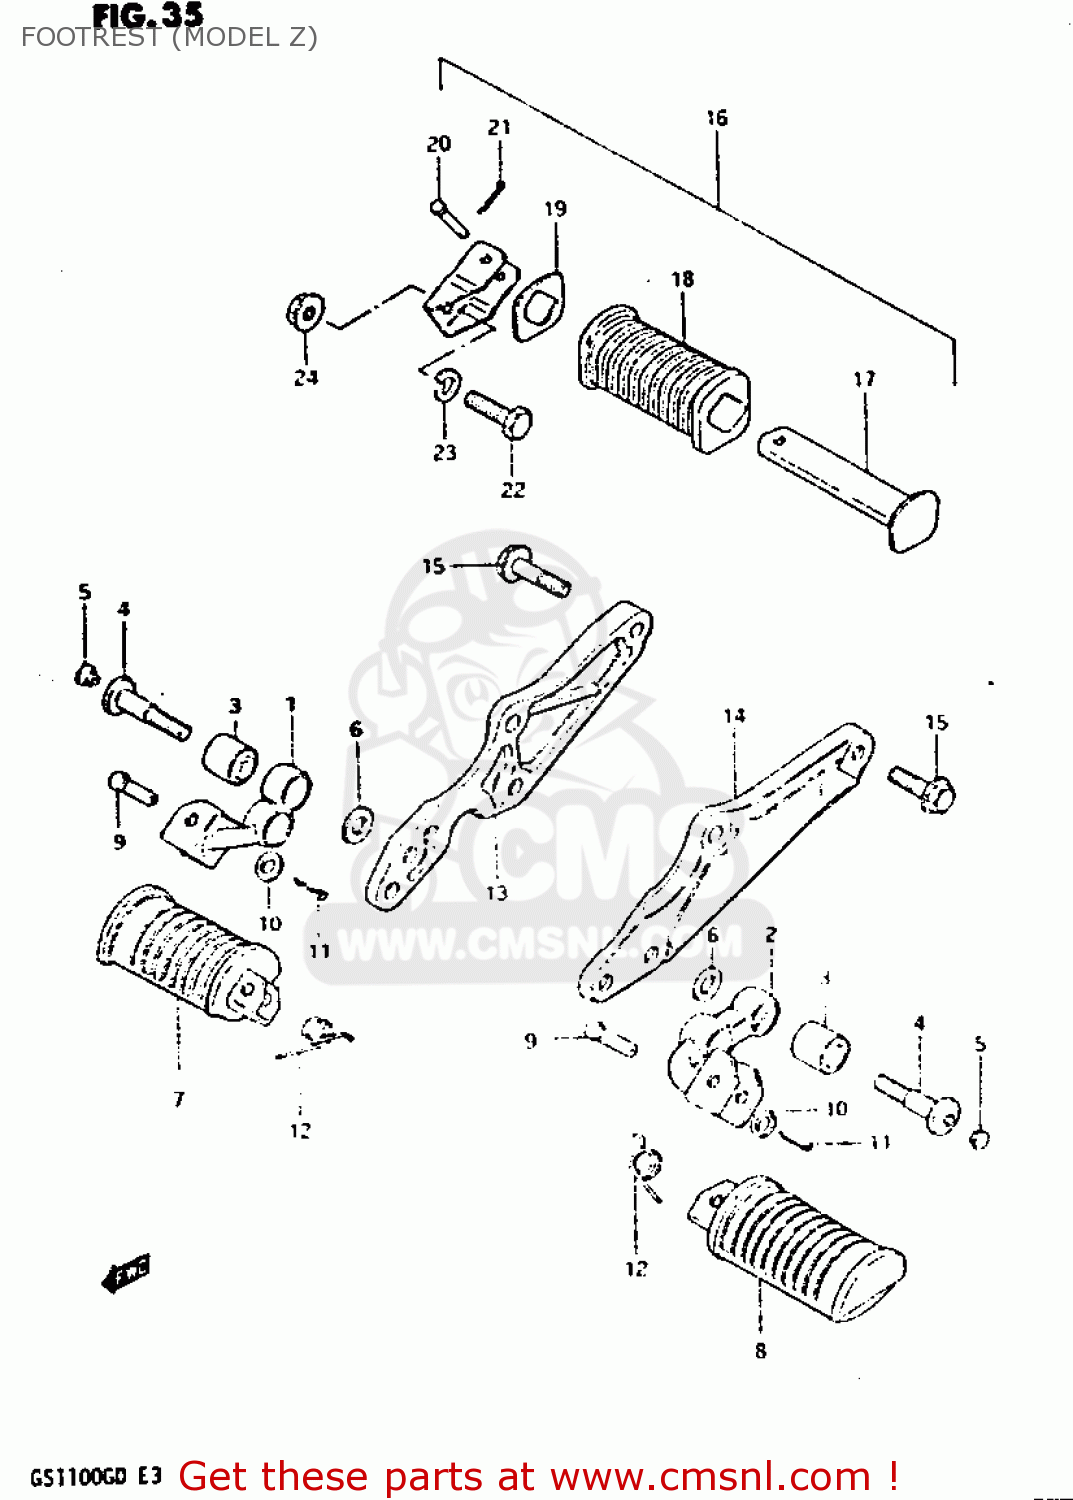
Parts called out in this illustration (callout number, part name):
1	BAR,FRONT FOOTREST,RIGHT
2	BAR,FRONT FOOTREST,LEFT
3	BUSH
4	BOLT(10X50)
5	CAP
6	WASHER(10.5X20X3.2)
7	RUBBER,PILLION FOOTREST,R
8	RUBBER,PILLION FOOTREST,L
9	PIN
10	WASHER
11	PIN 20X20
12	SPRING
13	BRACKET,MUFFLER,RIGHT
14	BRACKET,MUFFLER,LEFT
15	BOLT
16	FOOTREST ASSEMBLY,REAR,LEFT
17	BAR,REAR FOOTREST,LEFT
18	RUBBER,RR FOOTREST
19	WASHER,RR FOOTREST RUBBER
20	PIN
21	PIN 20X20
22	BOLT,M10X1.25X
23	WASHER,LOCK,10
24	NUT
